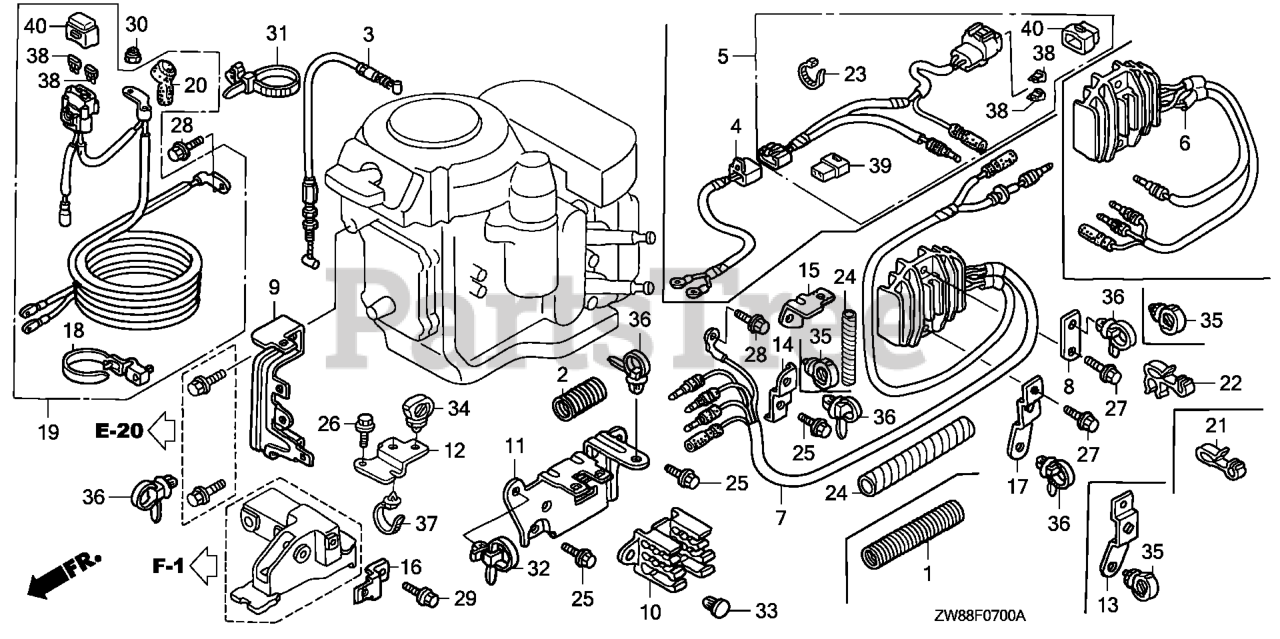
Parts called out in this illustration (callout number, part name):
1	TUBE, CORRUGATED (10MM)
3	CABLE, NEUTRAL STARTING
8	BRACKET, CLIP F
9	BRACKET, CONNECTOR A
10	BRACKET, CONNECTOR (B)
11	BRACKET, CONNECTOR (C)
11	BRACKET, CONNECTOR C
13	BRACKET, CLIP D
14	BRACKET, CLIP B
21	CLAMP, CENTER CORD
25	BOLT, FLANGE (6X14) (CT200)
27	BOLT, FLANGE (6X14) (CT200)
32	STRAP, CABLE (118MM) *NH1L* (Honda Code 1170653). (BLACK)
33	CLIP, ANCHOR
35	CLIP, HARNESS
36	CLIP, HARNESS BAND (151.5MM) (NATURAL)
